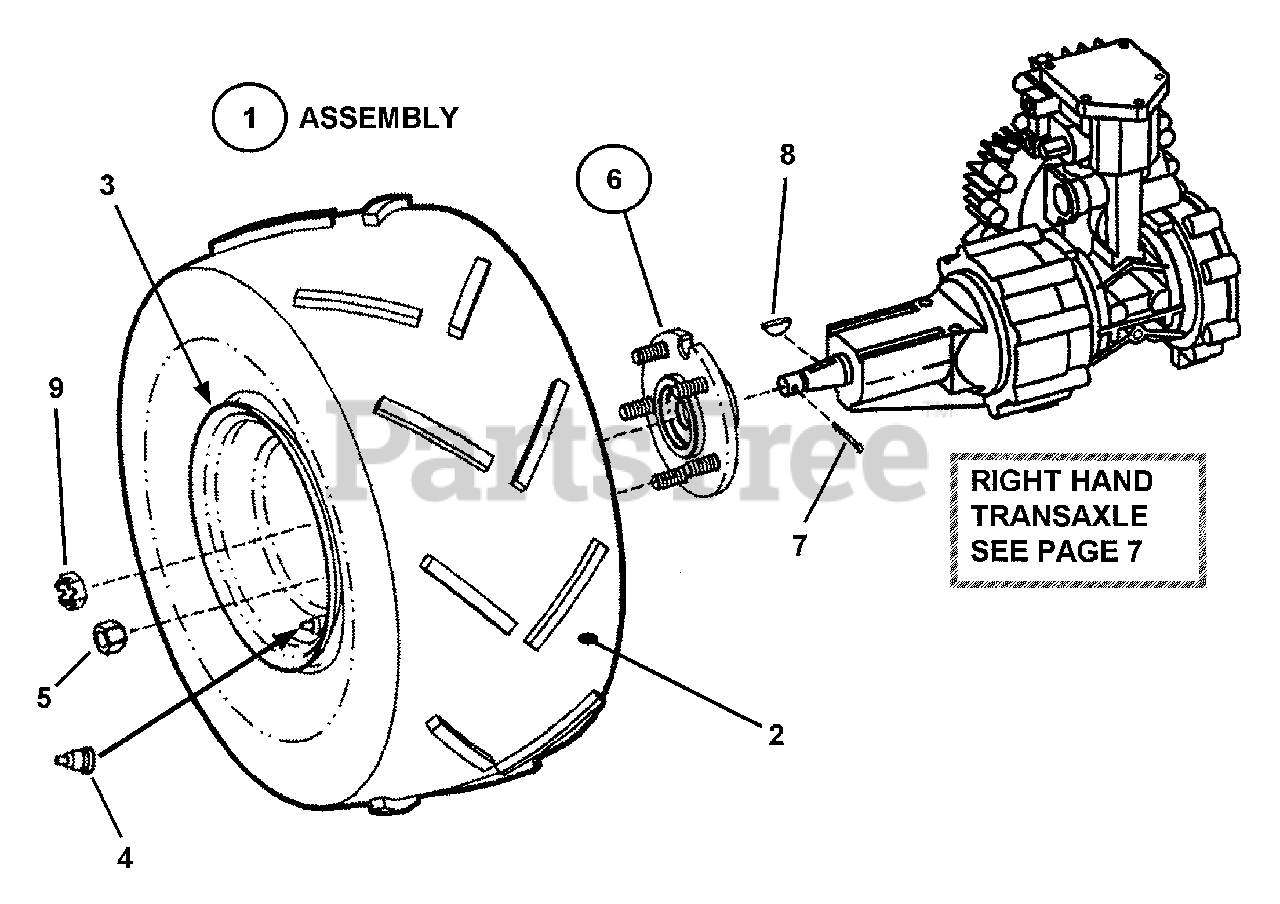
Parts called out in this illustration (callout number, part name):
2	TIRE, 21 x 10.00-8 4 ply "All Terrain"
3	RIM, 8" Dia. X 7-3/4"
4	VALVE, Air
5	NUT, 1/2-20 Lug
6	ASSEMBLY, Wheel Hub
7	PIN, Cotter, 9/64 x 1-1/2
8	KEY, #806 Woodruff
9	NUT, 3/4-20 Slotted Hex
